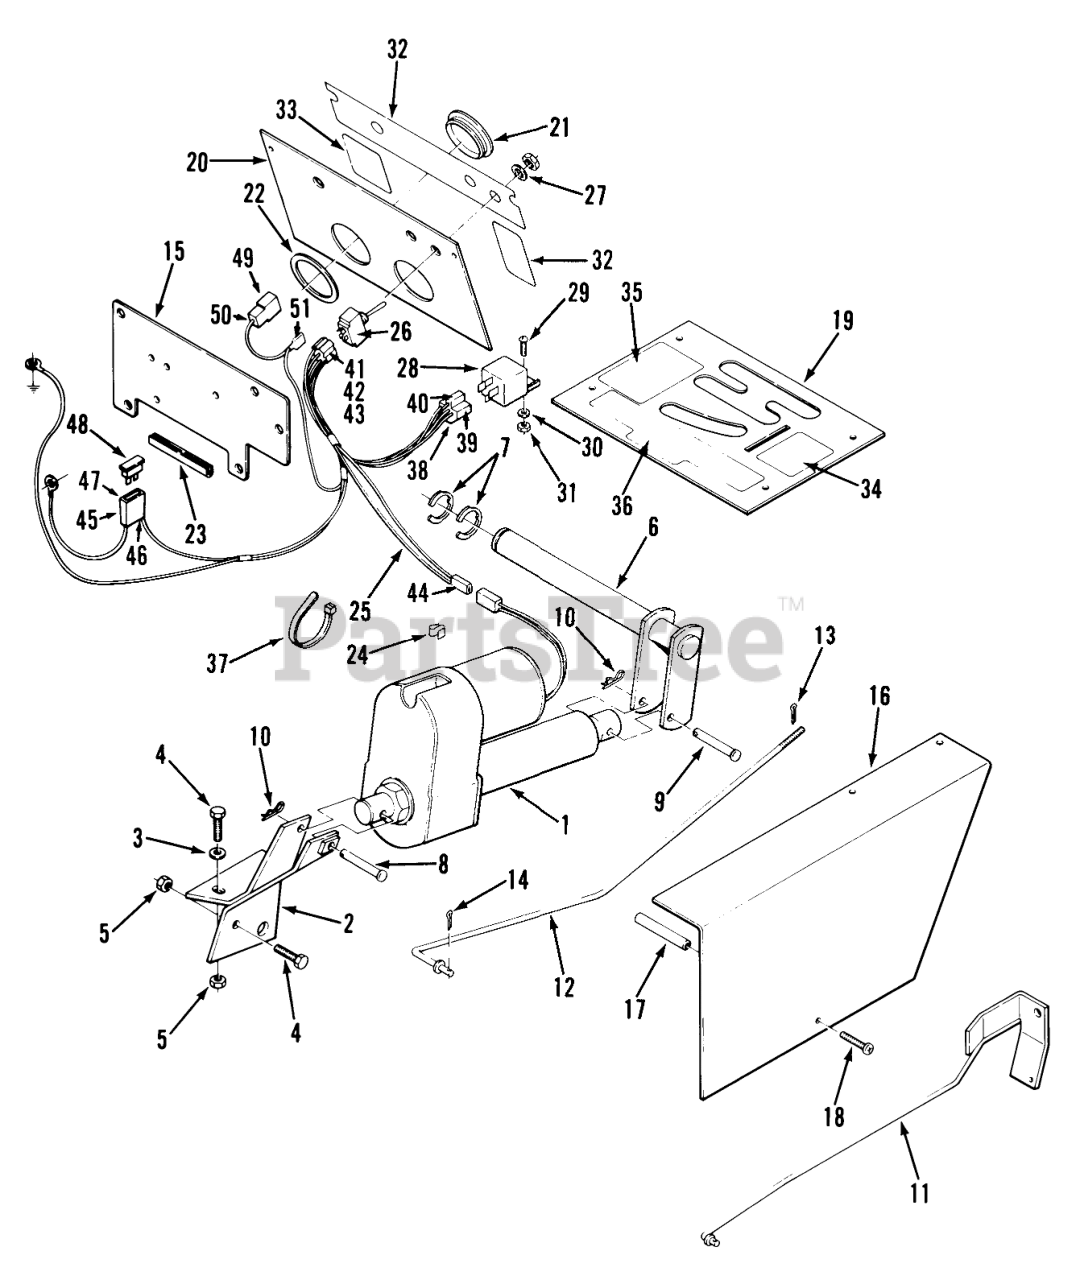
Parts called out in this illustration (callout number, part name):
1	Linear Actuator
2	Lift Bracket
3	Washer
4	BOLT
5	Nut
6	ASSY LIFT ARM B
7	Retainer
8	Clevis Pin 1/2 x 2 3/4
9	CLEVIS PIN
10	Hairpin Cotter
11	Brake Rod
12	ROD CLUTCH R
13	Cotter Pin
14	Pop Rivet
15	PLATE FRONT HOODS B
16	COVER LH R
17	Spacer
18	Pan Head Screw 1/4-20 x 1 3/4
19	PLATE SHIFT PATTE B
20	Hoodstand Plate
21	PLUG - HOLE
22	Backup Washer
23	EDGE TRIM 2" 102896
24	SPEED CLIP
25	WIRING HARNESS
26	SWITCH
27	Washer
28	RELAY
29	Screw
30	Washer
31	Nut
32	DECAL BACK PLATE
33	DECAL PTO
34	DECAL-PARKING, BRAKE
35	DECAL-SHIFT PATTERN
36	DECAL CAUTION
37	PLASTIC TIE
38	Connector Body (Part of Item 10)
39	Female Terminal (Part of Item 10)
40	TERMINAL FEMALE
41	CONNECTOR 5 WAY
42	Terminal
43	TERMINAL-TAB RCPT
44	CONNECTOR BODY B
45	AUTO-FUSEBLOCK TERM
46	TERMINAL FUSE
48	FUSE-BLADE, 25 AMP
49	Connector Body
50	Connector Part of 5
51	Terminal
